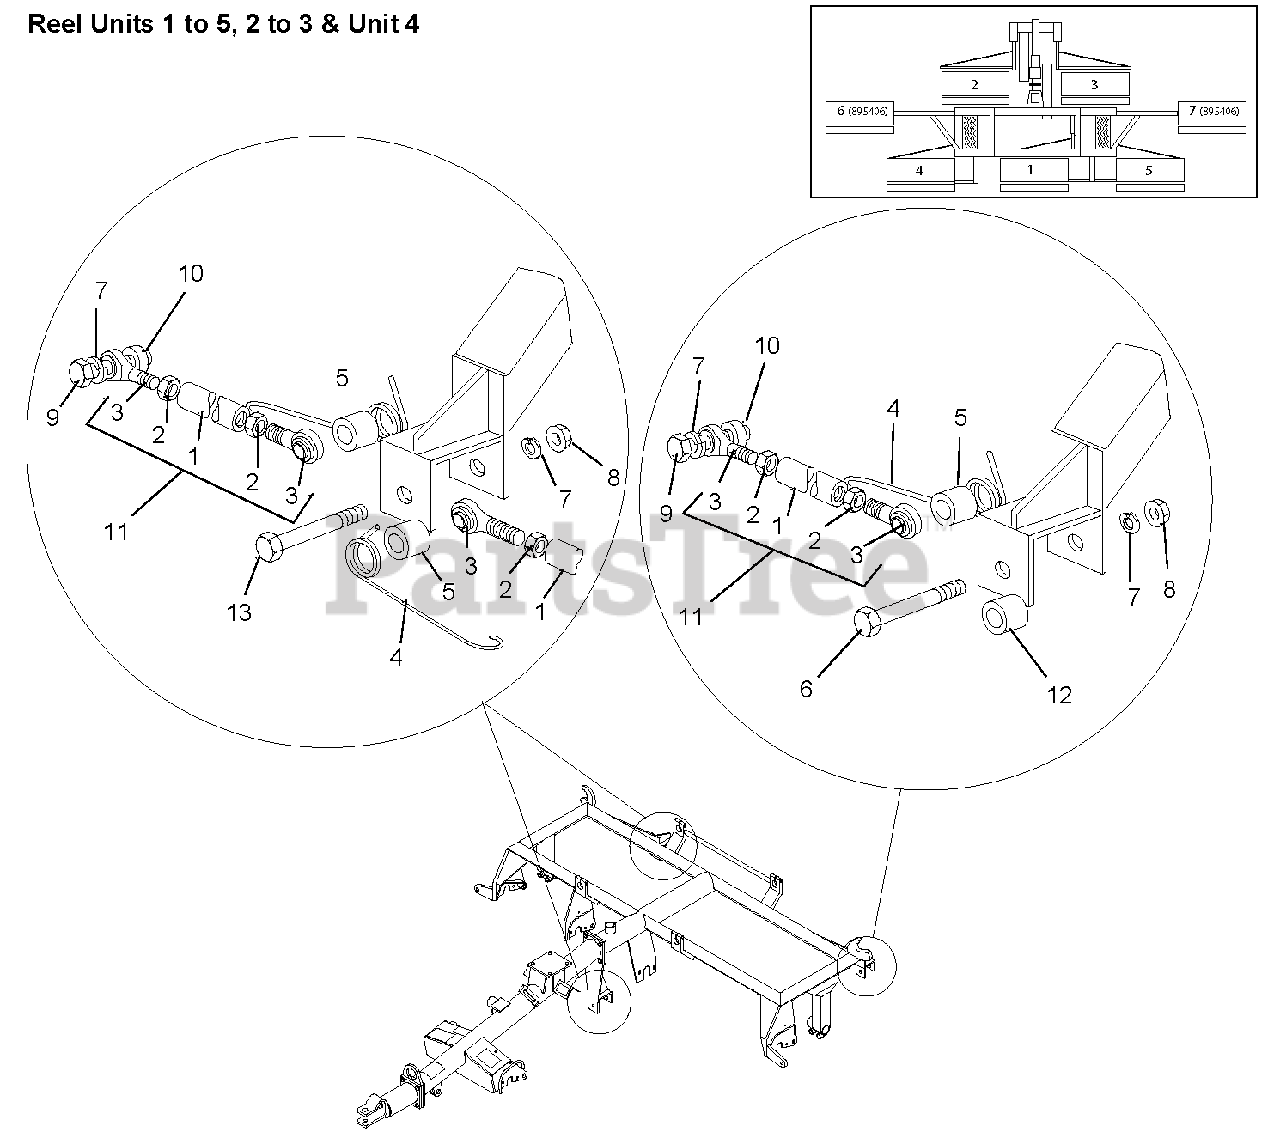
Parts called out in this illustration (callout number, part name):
1	Tie Rod, Rear
2	Nut, Hex .625-18 Right Hand Thread
3	Rod End, .625 Bore, Left Hand Thread
4	Spring, Compensator .25
5	Spacer, Compensator Long
6	Cap Screw, Hex Head .625-11 x 3.75
7	Washer, Lock .625
8	Nut, Hex .625-11
9	Cap Screw, Hex Head .625-11 x 2
11	Tie Rod Assembly, Short
12	Spacer, Compensator Short
13	Cap Screw, Hex Head .625-11 x 4.75
